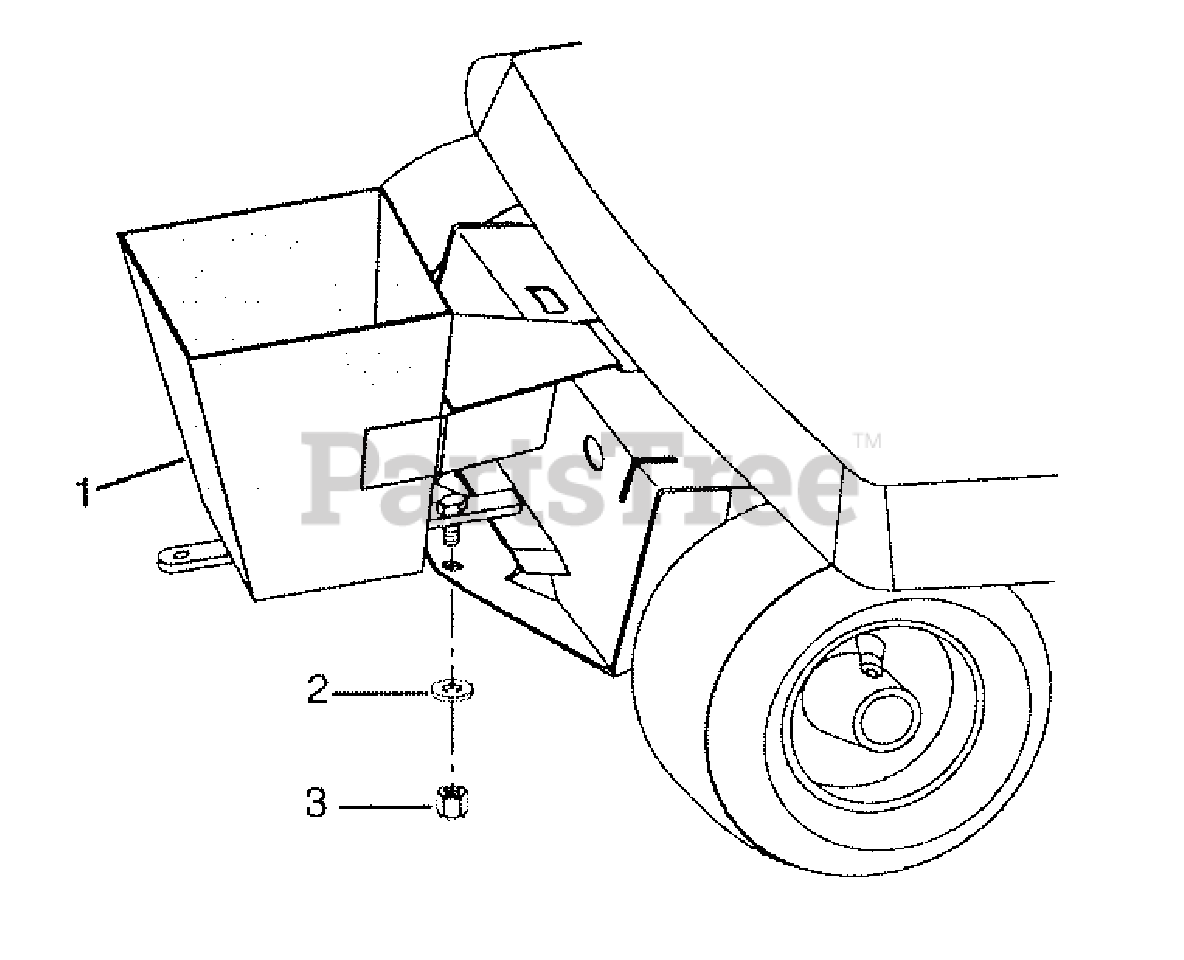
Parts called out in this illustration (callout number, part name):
1	Box Weight
2	Washer-Flat-Steel .511 x 1.44 x .125
3	Nut-Locking-Center .50-13
